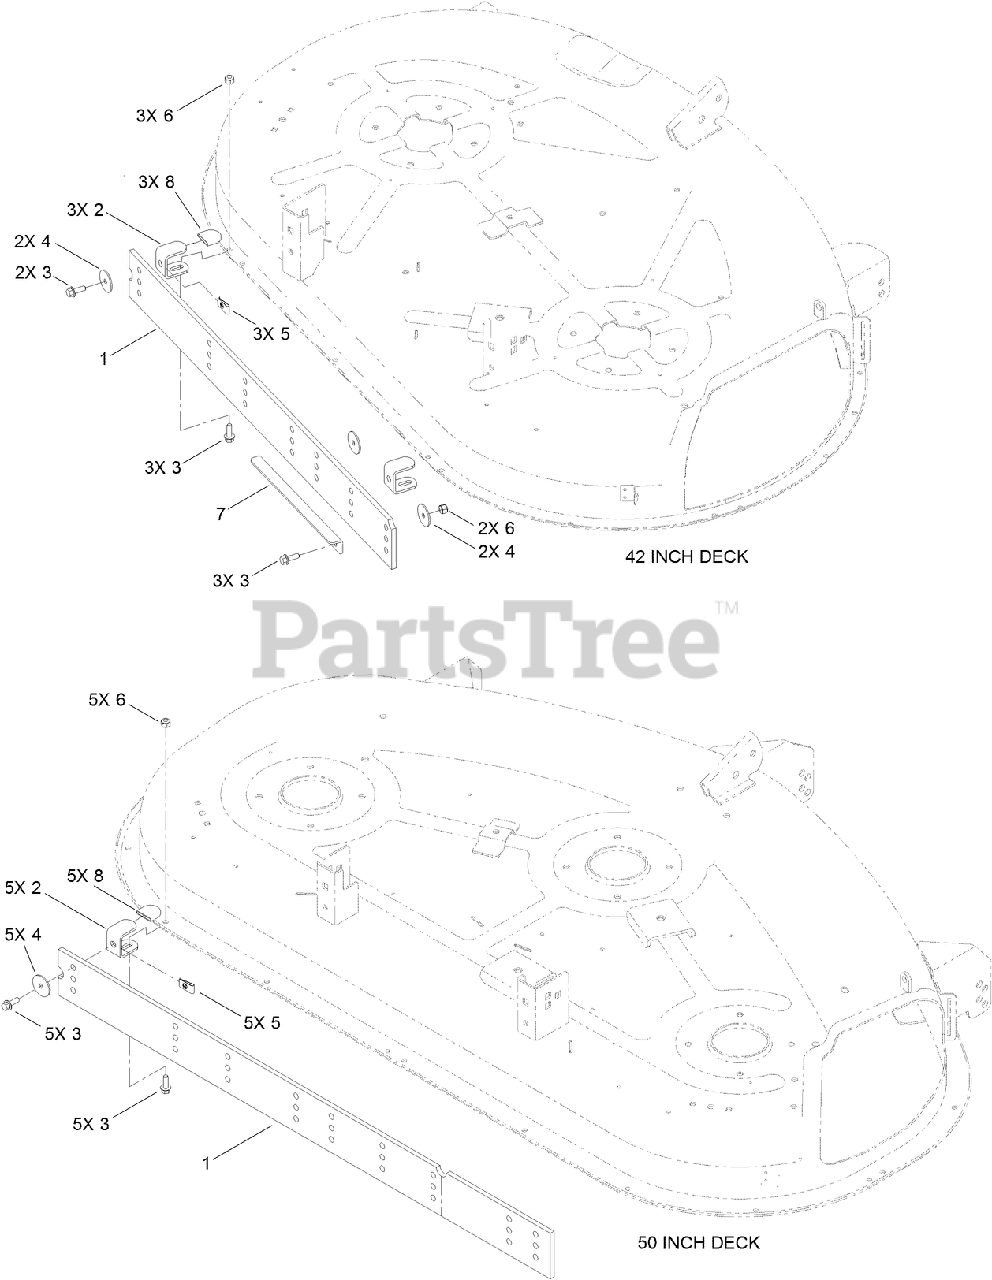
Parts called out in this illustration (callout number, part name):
2	BRACKET-MOUNTING
3	SCREW-HHF
4	WASHER-FLAT
5	NUT-SPEED
6	NUT-LOCK, NI
